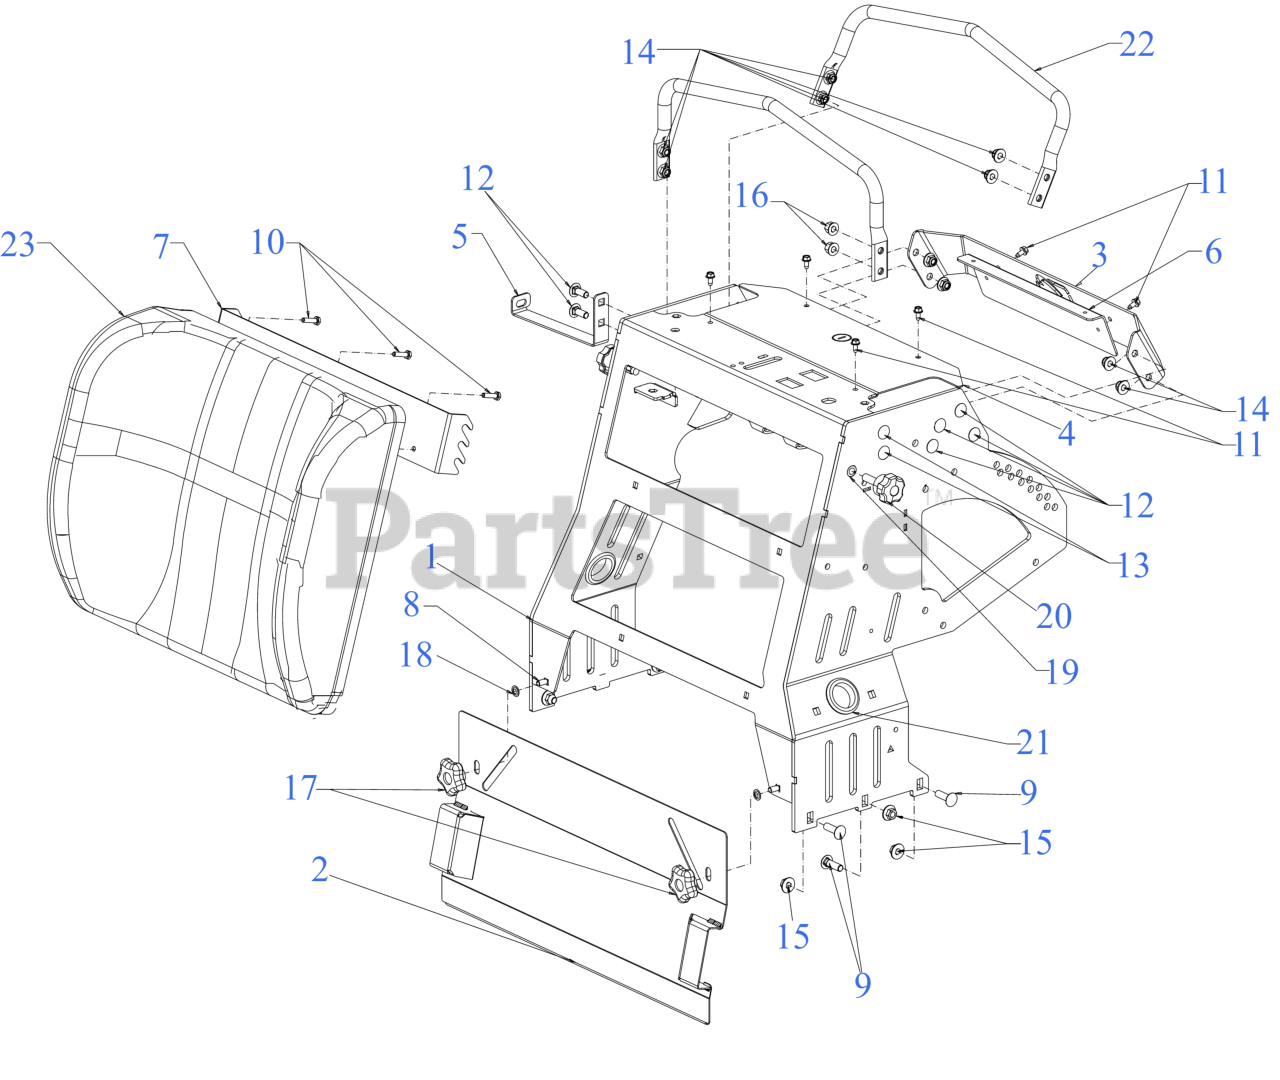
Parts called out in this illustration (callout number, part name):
1	CONTROL BASE
2	PANEL COVER
3	BASE CONTROL
4	DASH PANEL
5	TANK SUPPORT BRACKET
6	DASH SUPPORT
7	PAD MOUNT
8	CARRIAGE BOLT 5/16-18 x .75
9	CARRIAGE BOLT 3/8-16 X1.25 GR5
10	SCREW 1/4-20 X1.00 GR5
11	SCREW 1/4-20 X.500
11	SCREW 1/4-20X.625
12	CARRIAGE BOLT 3/8-16 x 1.00 GR5
13	CARRIAGE BOLT 3/8-16 x .75
15	FLANGE LOCK NUT
16	NUT-CTRLCK FLG HEX
17	STAR KNOB 5/16-18
19	RIV NUT 3/8-16
20	SEAT ADJUST KNOB 3/8-16 x 1.50
21	RUBBER GROMMET (1.50X2.13X.563)
22	TUBE
